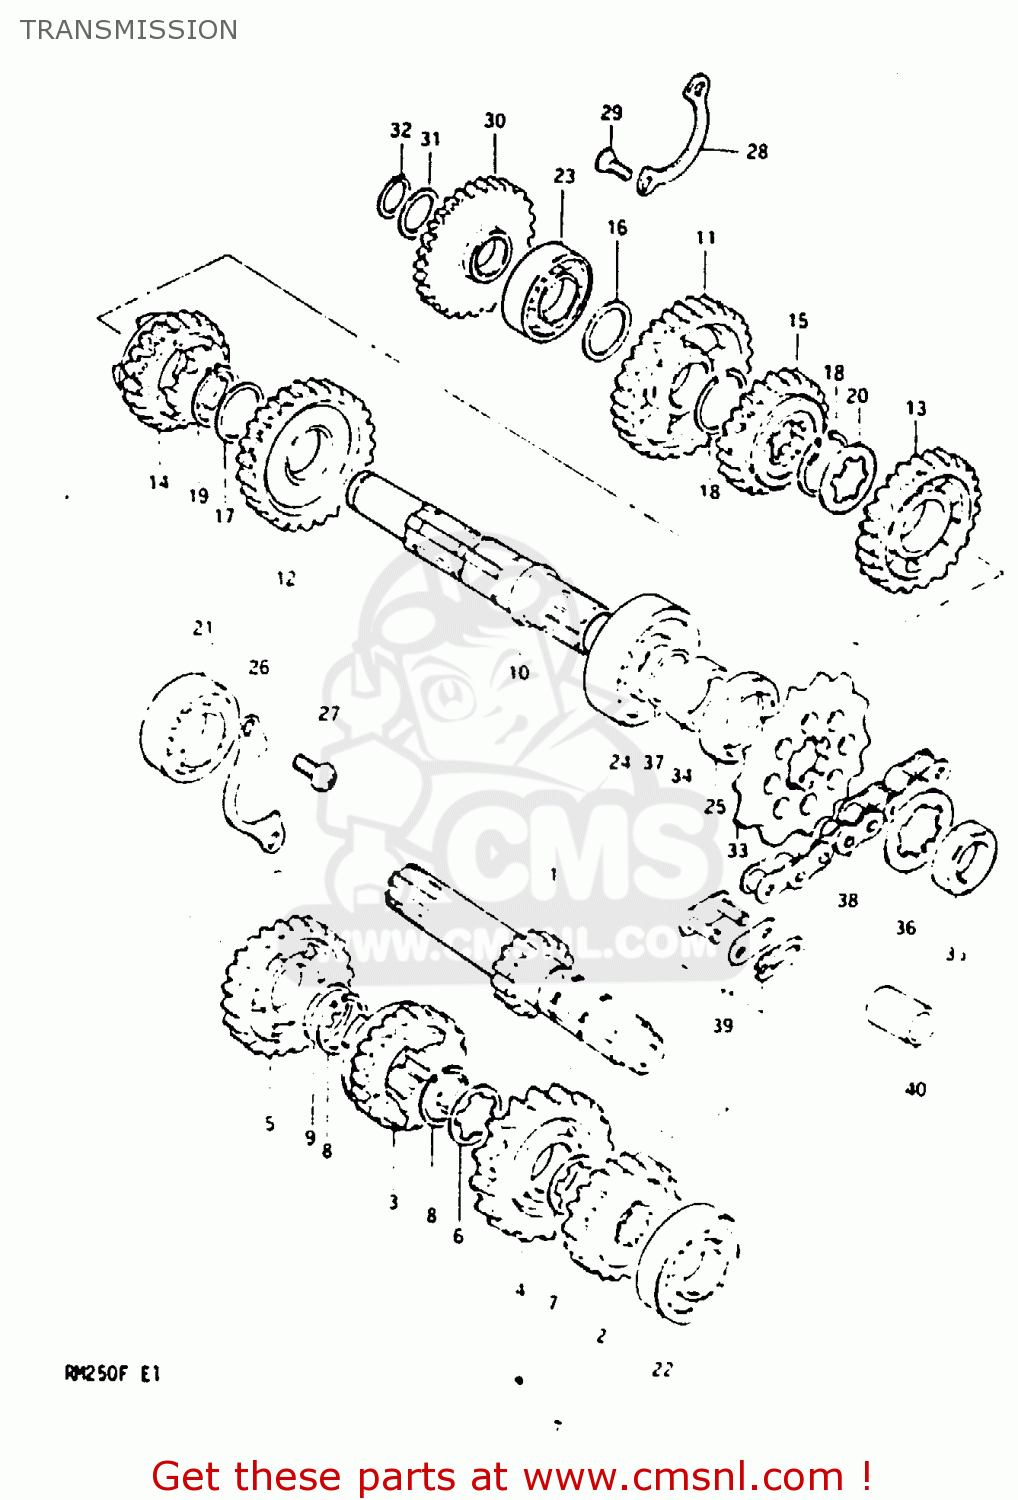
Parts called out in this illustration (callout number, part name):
1	SHAFT,COUNTER
2	GEAR,SECOND DRIVE
3	GEAR,THIRD DRIVE
4	GEAR,FOURTH DRIVE
5	GEAR,FIFTH DRIVE
6	WASHER,LOCK
7	WASHER,LOCK
8	CIRCLIP
9	SHIM(22X28X0.5)
10	SHAFT,DRIVE
11	GEAR,FIRST DRIVEN
12	GEAR,SECOND DRIVEN
13	GEAR,THIRD DRIVEN
14	GEAR,FOURTH DRIVEN
15	GEAR,FIFTH DRIVEN
16	WASHER
17	SHIM
18	CIRCLIP
19	CIRCLIP,25MM
20	WASHER
21	BEARING(20X52X15)
22	BEARING(17X40X12)
23	BEARING(17X40X12)
24	BEARING
25	SEAL,OIL(32X42X6)
26	PLATE,COUNTERSHAFT BEARING
27	SCREW 6X12
28	PLATE,DRIVESHAFT BEARING
29	SCREW
30	GEAR,KICK STARTER IDLE
31	WASHER
32	CIRCLIP
33	SPROCKET,ENGINE
34	SPACER(22X32X9.5)
35	NUT
36	WASHER,LOCK
37	O RING(D:1.7,ID:22)
38	CHAIN ASSEMBLY,DRIVE
39	JOINT ASSEMBLY,CHAIN
40	SPACER(12X20X15.3)
